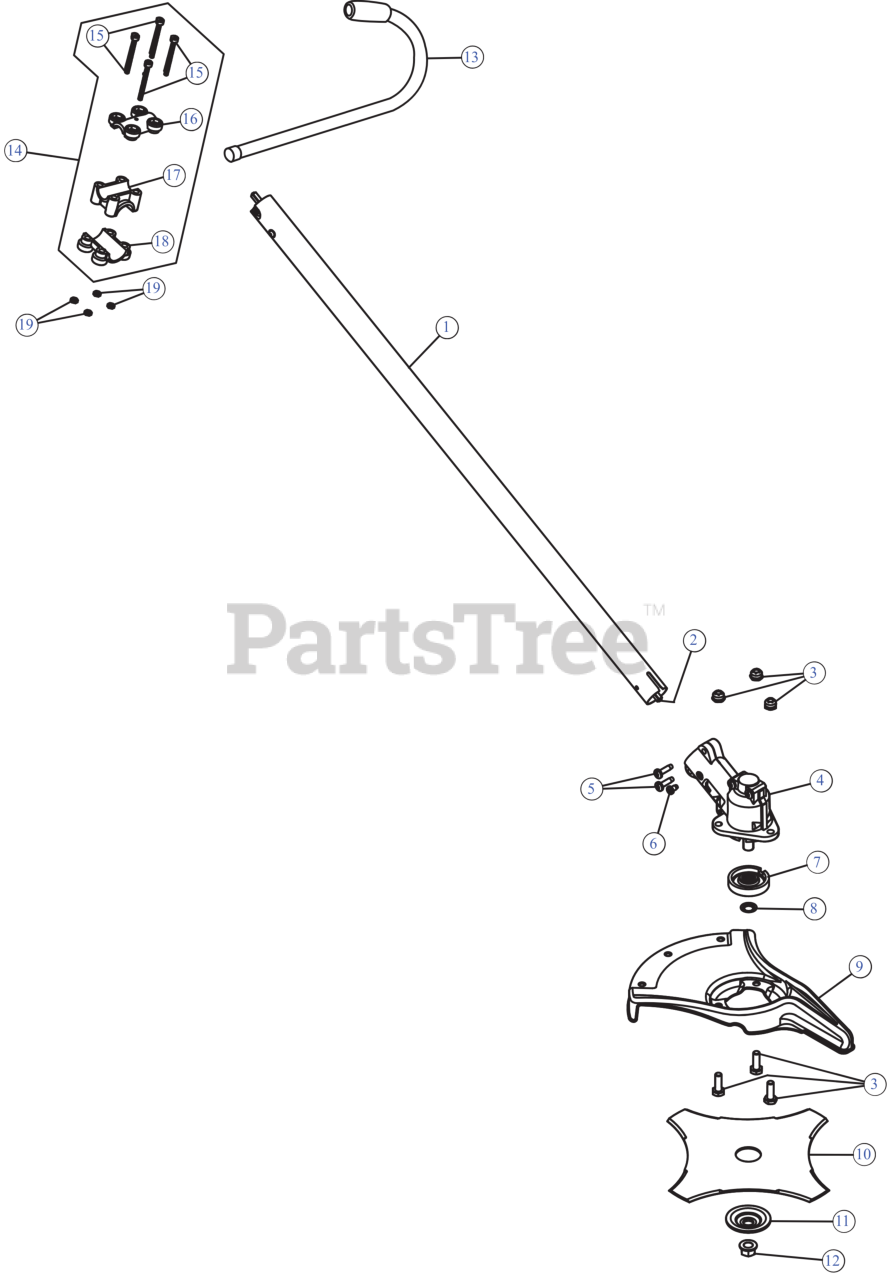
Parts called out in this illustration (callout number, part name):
1	LOWER DRIVE SHAFT HOUSING ASSEMBLY
2	SHAFT, DRIVE
3	SCREW SET-GUARD MT
4	GEARBOX ASSEMBLY
5	SCREW #
6	SCREW, 8-32 x .312 P
7	SPACER-GEARBOX
8	PALNUT:3/8" DIAM
9	SHIELD-BLADE CAST
10	BLADE 4-TOOTH
11	WASHER-BLADE CLAMP BRUSH CUT
12	BLADE LOCK NUT
13	HANDLE ASSEMBLY-JAY
14	HANDLE BRACKET ASSEMBLY
15	CLAMP SCREW
16	HANDLE UPPER CLAMP
17	HANDLE MIDDLE CLAMP
18	HANDLE LOWER CLAMP
19	NUT-CLAMP
